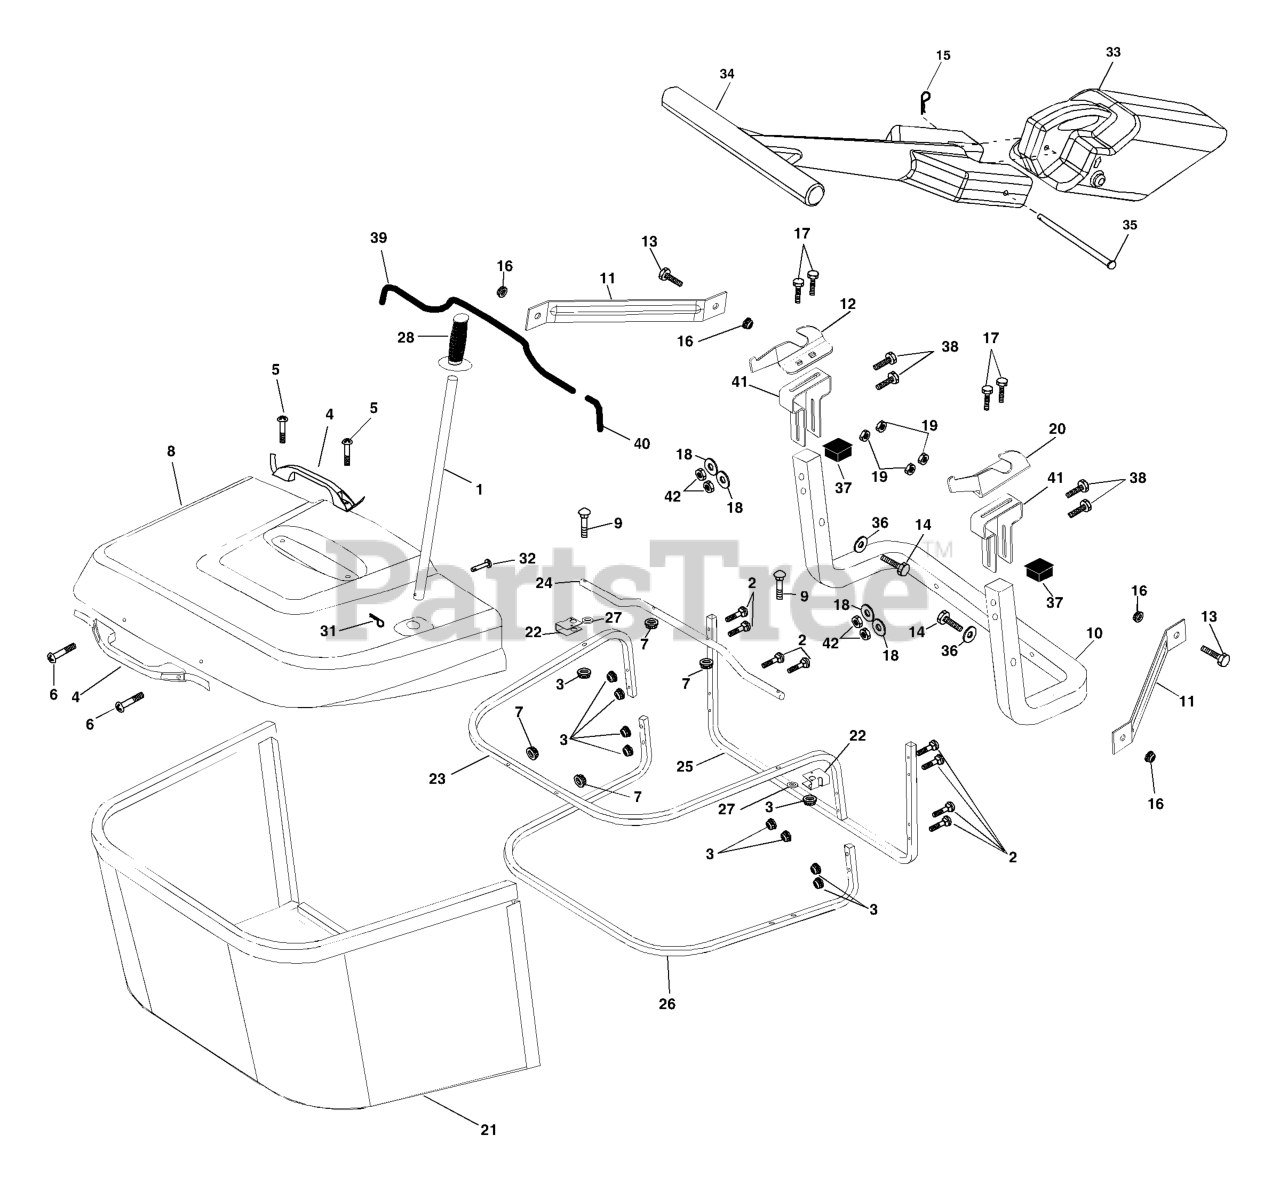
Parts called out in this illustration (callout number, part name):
1	TUBE HANDLE BAGGER
2	Bolt Carriage 1/4-20 x 2.0 Gr.5
3	NUT T
4	HANDLE.BAGGER.W/LVRS.BLK.CRD
5	SCREW.PAN.HEAD
6	REPL BY 532 75 00-29
8	COVER
9	Bolt Carriage 1/4-20 x 2.25d x Gr.5
10	TUBE
11	BRACKET.SUPPORT.UPPER.BAG.CRD
13	BOLT
14	Bolt Hex 3/8-16 x 2-1/2 Gr.5
15	RETAINER-SPRNG RB
16	NUT LOCK FLG 3/8-16 UNC
17	RP BOLT 5/16-18 X3/4 ZN/YEL GR
18	WASHER M
19	NUT LOCK HEX FLANGE 5/16-18
20	BRACKET
21	BAG
22	BRKT.SIDE.BAG.CRD
23	TUBE.UPPER.BAG.CRD
24	TUBE.PIVOT.BAG.CRD.BLACK
26	TUBE.LOWER.BAG.CRD
28	Grip Handle Black
31	RETAINER M
32	RIVET,DRILLED
33	PLUG.MULCHER.92 CRD
34	HANDLE.MULCHER.92.CRD (2 2)
36	WASHER
37	Plug Support Bagger CRD
38	BOLT.5/16-18X2.5
39	TRIM
40	TRIM
41	BRKT.VERT.ADJ.BAGGER.CRD
42	NUT.71038.31-18.HEX.NYLOCK
